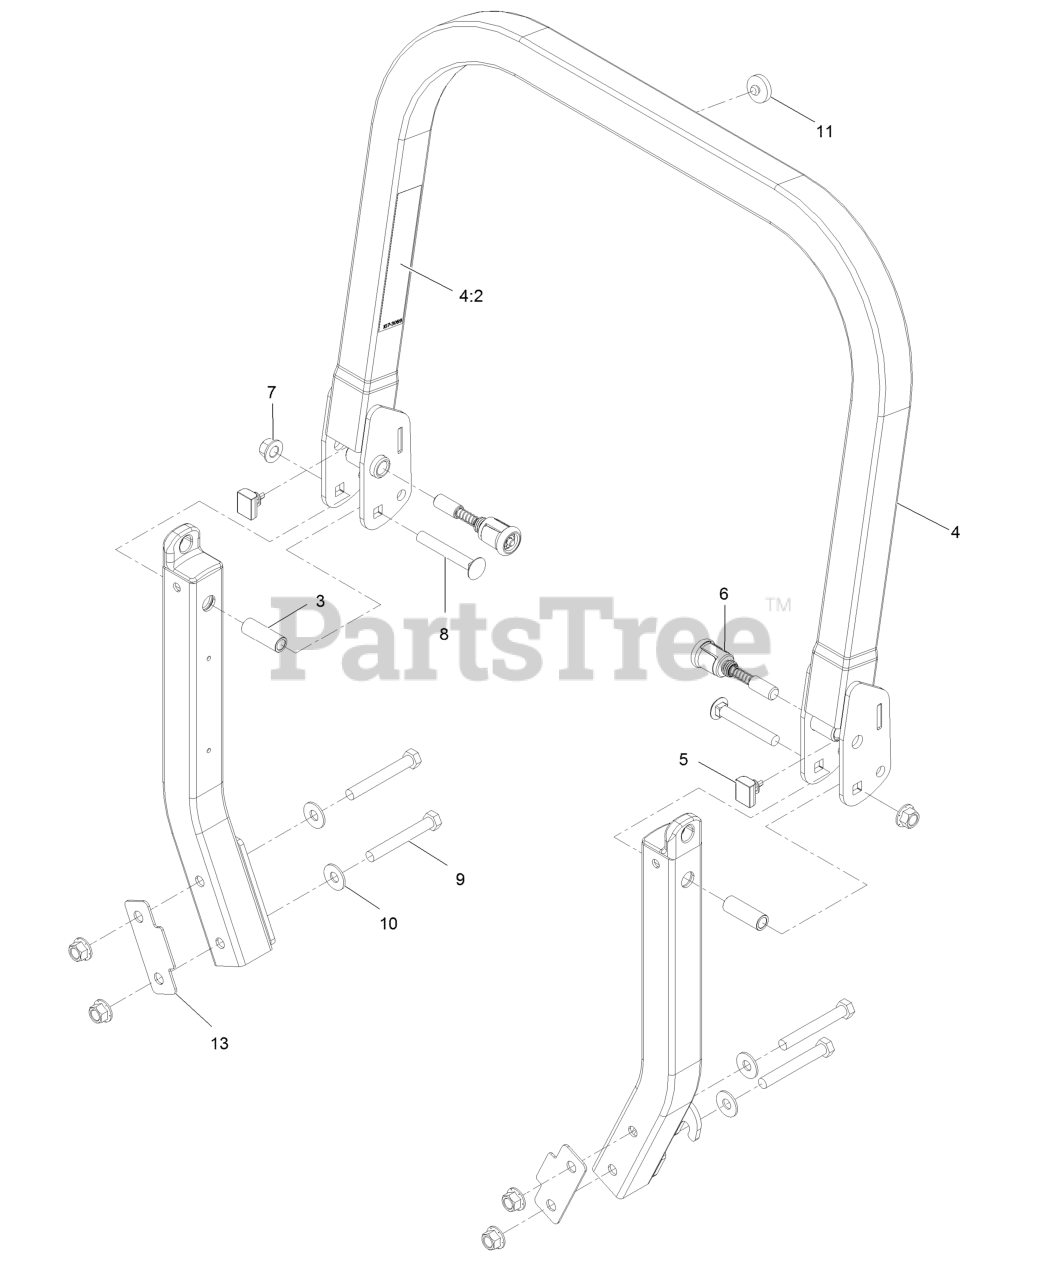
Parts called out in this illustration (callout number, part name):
4	UPPER ROPS ASM
4:2	DECAL-WARNING
5	BUMPER-ROPS
6	PIN-SPRING
7	Nut-Lock 1/2-13
8	SCREW-CARR
9	WASHER-LOCK
10	WASHER-SPRING
11	BUMPER-PUSH-IN, RUBBER
